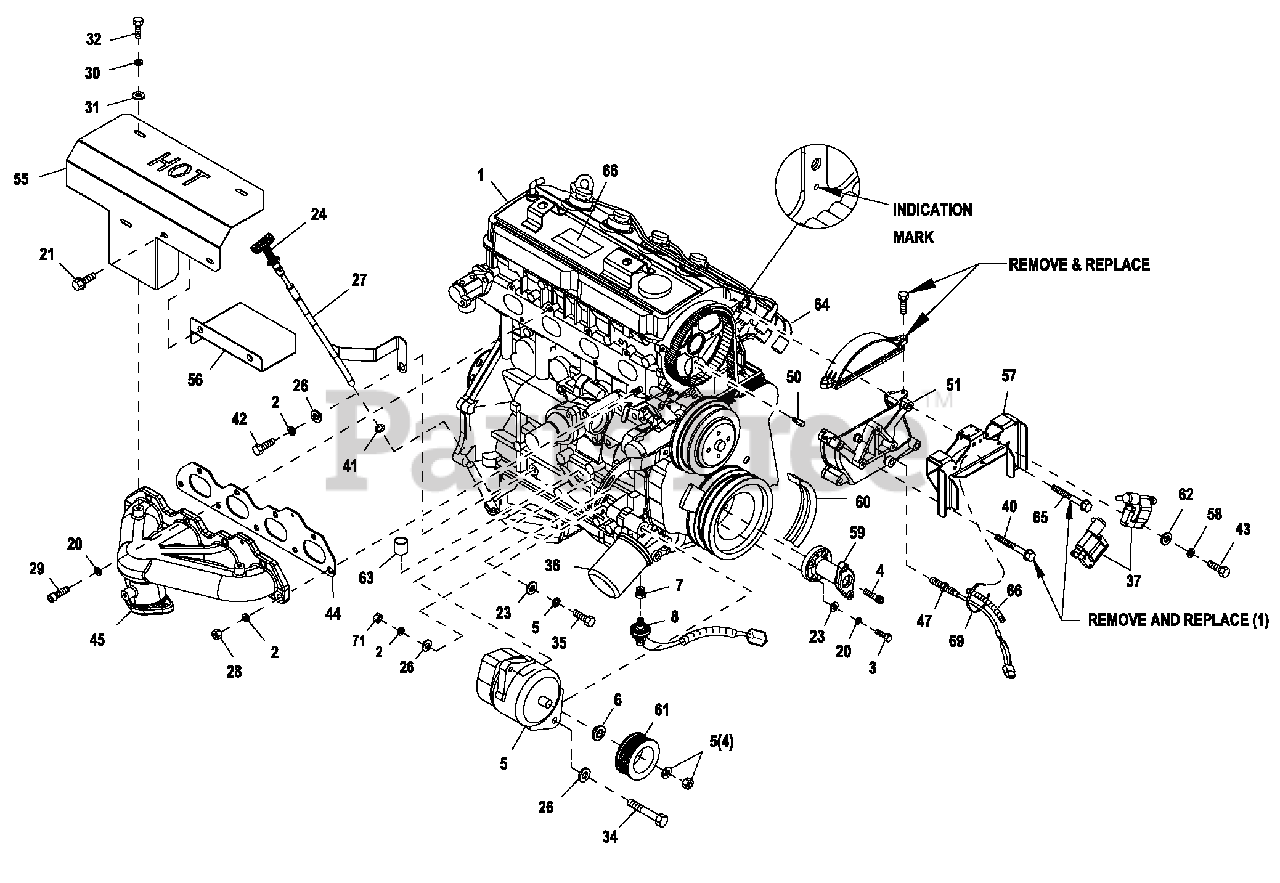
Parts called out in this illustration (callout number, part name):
1	ENGINE 2.4LG2 CERTIFIED
2	WASHER LOCK M10
3	SCREW HHC M8-1.25X35 G8.8
4	SCREW SHC M14-1.5X 35 G10.9
5	ALTERNATOR DC W/OUT PULLEY
6	SPACER DC ALTERNATOR PULLEY
7	ADAPTOR 1/8 NPTF TO 1/8 BSPT
8	HARN LOW OIL PRESS SWITCH ASSY
9	WASHER NYLON .565
10	ADAPTER M14-1.50X 3/8 NPT
11	BARBED EL 90 3/8 NPT X 3/8
12	CLAMP HOSE .38- 87
13	HOSE DRAIN ASSY 28"
14	WASHER FLAT .531 ID X 1.062 OD
15	SCREW HHC M12-1.25 X 20 G10.9
16	SCREW HHC M10-1.25X45 G8.8
17	WASHER SHAKEPROOF EXT 7/16 STL
18	SCREW HHC M10-1.25X30 G8.8
19	SCREW SHC M8-1.25 X 30 G12.9
20	WASHER LOCK M8-5/16
21	SCREW THF M6-1 X 16 N WAZ/JS
22	TEMPERATURE SENDER
23	WASHER FLAT 5/16-M8 ZINC
24	ASSEMBLY DIPSTICK G2.4L
25	NUT HEX M8-1.25 G8 CLEAR ZINC
27	ASSY DIPSTICK TUBE 2.4 G2
28	NUT HEX M10-1.25 G8YELCHR
29	SCREW SHC M8-1.25 X 25 G12.9
30	WASHER LOCK M6-1/4
31	WASHER FLAT 1/4-M6 ZINC
32	SCREW HHC M6-1.0 X 12 G8.8
33	PLUG STD PIPE 1/4 STEEL SQ HD
34	SCREW HHC M10-1.5X 120 C8.8
35	SCREW HHC M8-1.25X 25 G10.9
36	FILTER 1.5L/2.4LG2 OIL
37	COIL-2.4LG2 IGNITION
38	HOSE 3/8 ID SINGLE BRAID (15" LG)
39	BARBED EL 90 1/4 NPT X 3/8
40	SCREW HHC M8-1.25X65 C8.8
41	O-RING SIZE 9.0MM X 2.0MM NITR
42	SCREW HHC M10-1.25X 20 C8.8
43	SCREW HHM #10-32X1-1/4
44	GASKET EXHAUST MANIFOLD
45	EXHAUST MANIFOLD G2 (MACHINE)
46	FLEX PLATE 2 POLE 2.4L G2
47	ASSY MAGPICKUP(3/8-24 MALE)
48	ADAPTER ENGINE 2.4L MACHINE
49	STARTER MOTOR 12V
50	CAM SENSOR PIN ASSY
51	COVER CAM GEAR G2 REWORKED
52	MANIFOLD INTAKE (MACHINED)
53	GASKET INTAKE MANIFOLD
54	SPACER 2.4L G2 FLEX PLATE
55	SHIELD HEAT
56	SHIELD HEAT SML
57	BRACKET ASM-2.4L COIL G2
58	WASHER LOCK #10
59	ADAPTER 2.4L CRANKSHAFT MACH
60	POLY V-BELT G2
61	PULLEY DC ALTERNATOR
62	WASHER FLAT #10 ZINC
63	PLUG TAPER
64	SPARK PLUG WIRE SET 2.4L G2 IG
65	SCREW HHC M8-1.25X70 G8.8
66	CONDUIT FLEX .25"ID
67	DECAL EMISSION CTRL INFO 2.4L
68	HARN ENG G2.4LG2 NEXUS
69	TIE WRAP UL 7.4"X .19" BLK
71	NUT HEX M10-1.5 G8 YEL CHR
